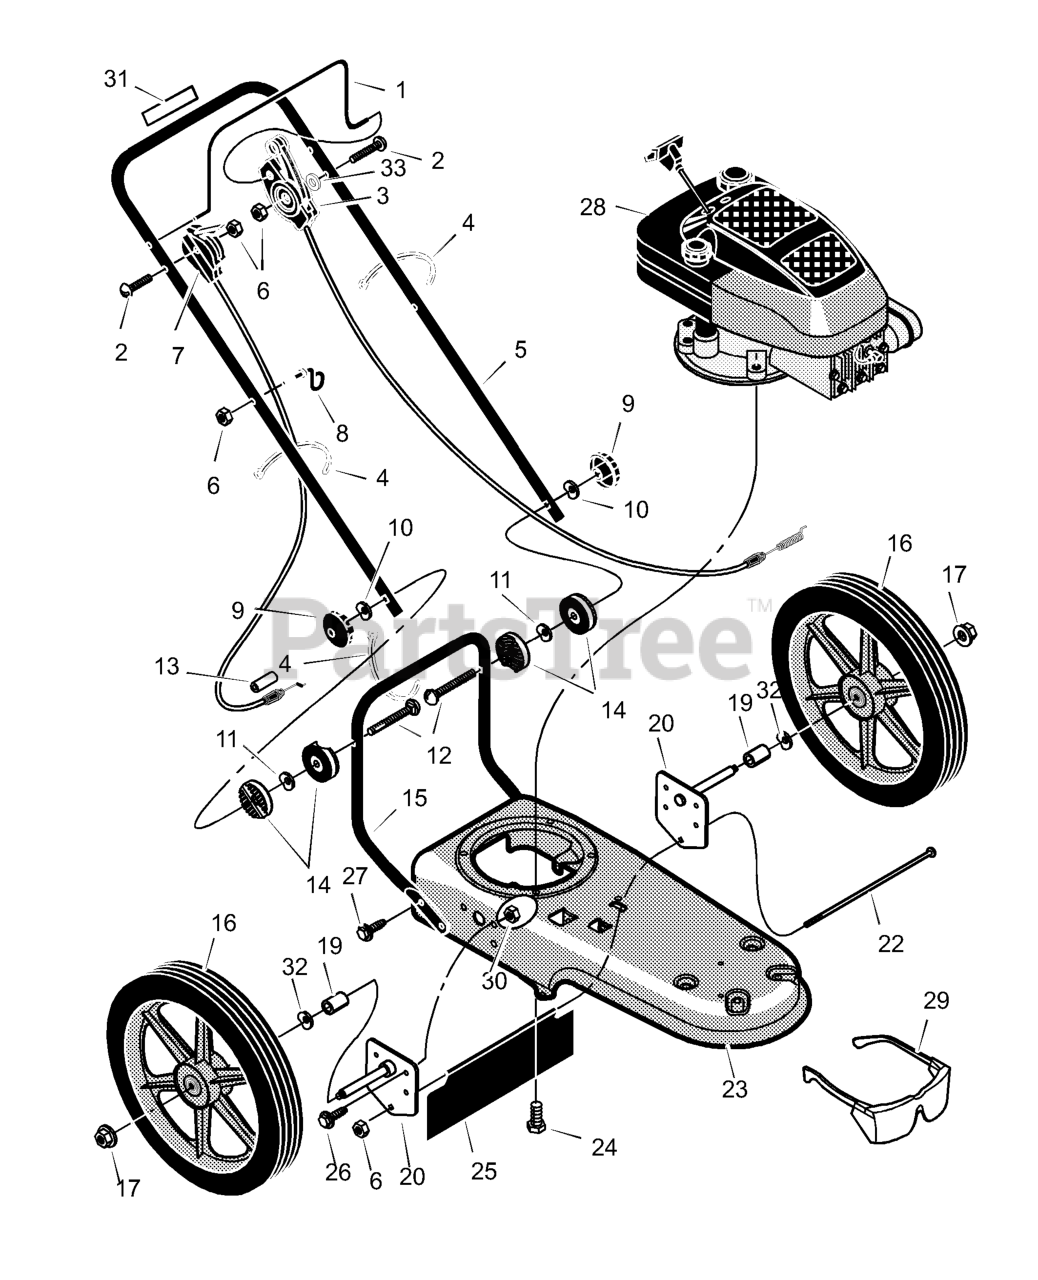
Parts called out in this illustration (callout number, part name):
1	LEVER, Stop
3	CABLE, Control Latching
4	TIE, Cable
7	CONTROL, Throttle
8	GUIDE, Rope
9	KNOB, Handlebar
11	WASHER, Spring
13	Stop, Throttle
14	PIVOT, Handlebar
15	HANDLEBAR, Lower
16	WHEEL & TIRE
17	NUT, Axle
20	ASSEMBLY, Axle & Bracket
22	BOLT, Carriage
25	SHIELD, Trailing
28	Engine
29	PROTECTION, Eye
31	DECAL, Engine Stop
31	SPACER, PM .26x.5x.2
32	WASHER, Spring
